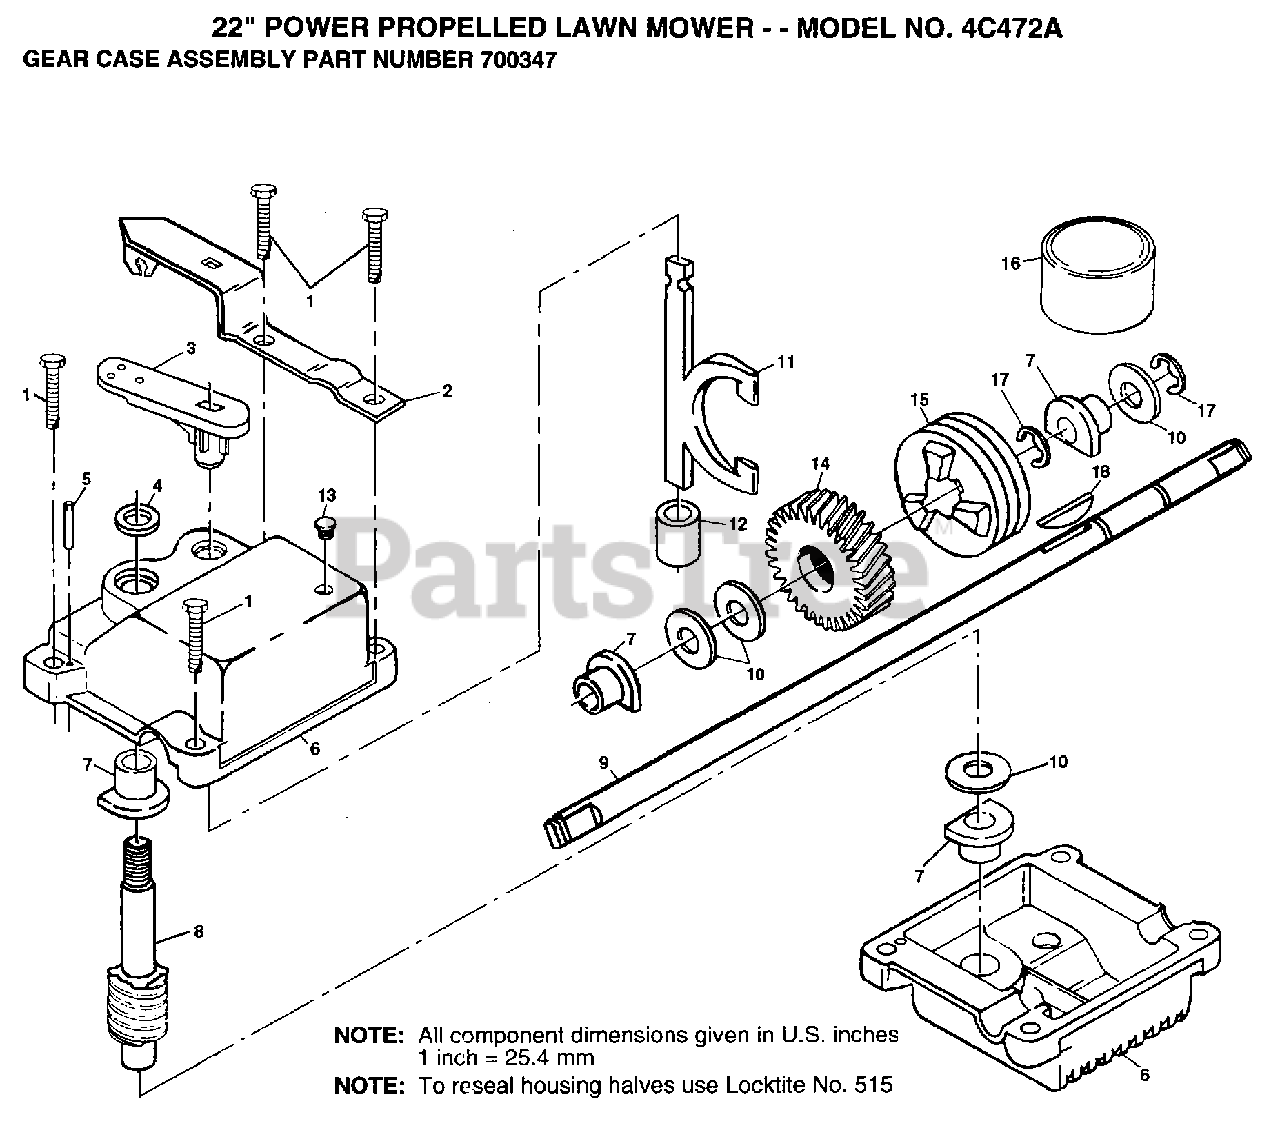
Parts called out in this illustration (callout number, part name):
1	SCREW.1/4-20
3	SHIFTER
4	SEAL
5	DRIVE LOK PIN
6	GEARCASE KIT
7	BEARING
8	SHAFT.WORM
9	SHAFT.DRIVE
10	THRUST WASHER
11	CLUTCH YOKE
12	BUSHING.GEAR BOX
13	PLUG PM
14	GEAR.HELICAL
15	CLUTCH JAW
17	RING T
18	HI PRO KEY
